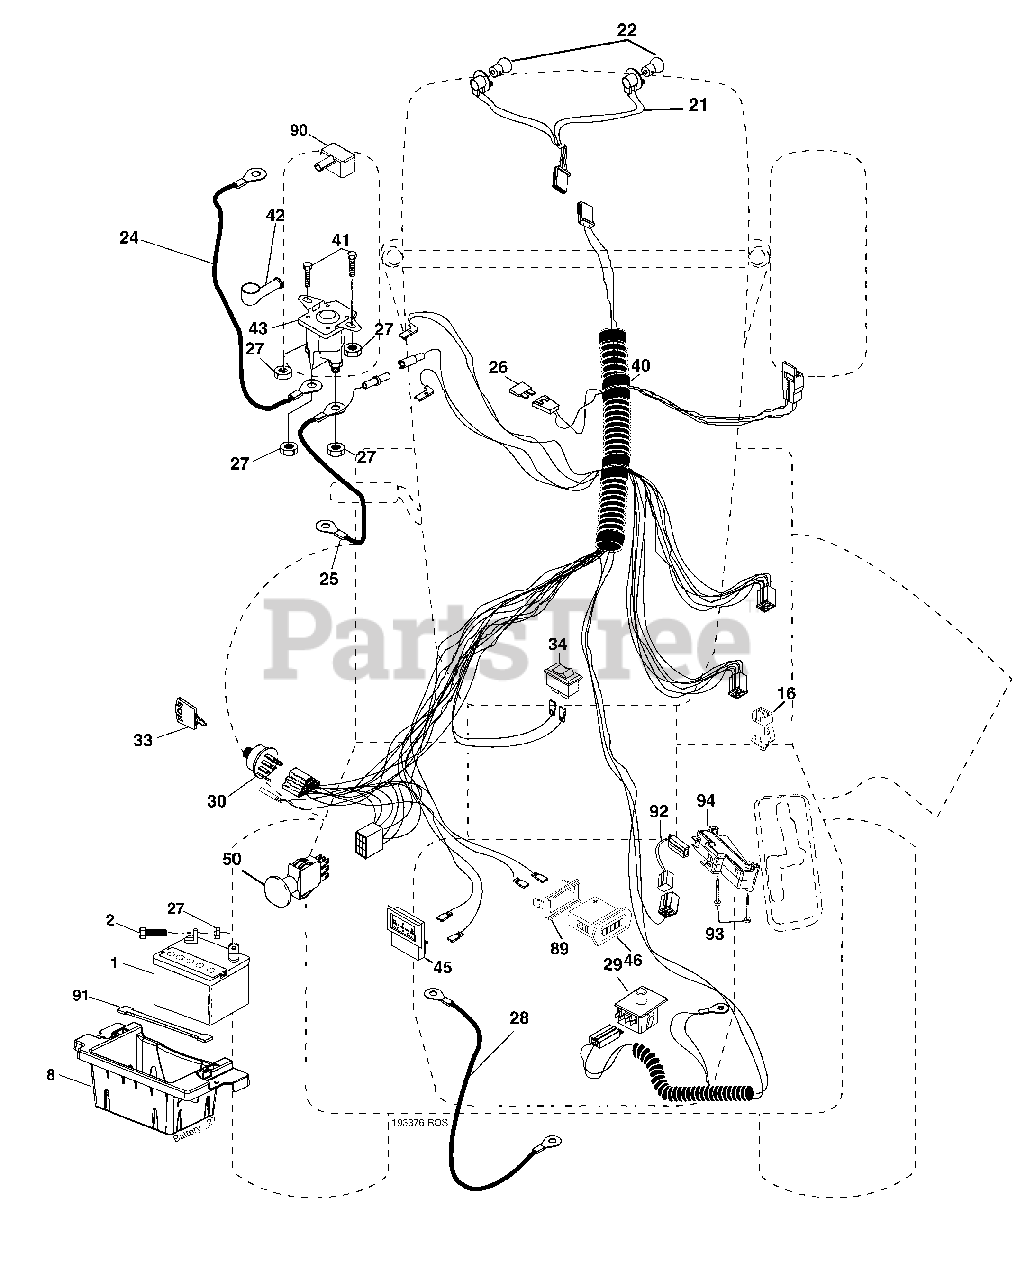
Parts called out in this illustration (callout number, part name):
1	Battery
2	Bolt Hex Hd 1/4-20 unc x 3/4
8	Box Battery
16	Switch Interlock Push-In
21	Harness Asm Light W/4152j
22	Bulb Light #1156
24	Cable Battery 6 Ga. 11" red
25	Cable Battery 6 Ga. 22" red w/16 wire
26	Fuse 20 AMP
27	Nut Keps Hex 1/4-20 unc
28	Cable Ground black
29	Switch Seat DP w/ROS
30	Switch Ign
33	Key Ign Molded Generic
34	Switch Light/Reset
40	Harness Ign.
41	Bolt 1/4-20 x 1/2
42	Cover Terminal Red
43	Solenoid
46	Hourmeter Snap-In
50	Switch PTO
89	Bracket Snap-In Hourmeter
90	Cover Terminal
91	Strap Battery
92	Harness Pigtail Revers Switch
93	Screw Plastic 10-14 x 2.0
94	Module Reverse ROS
